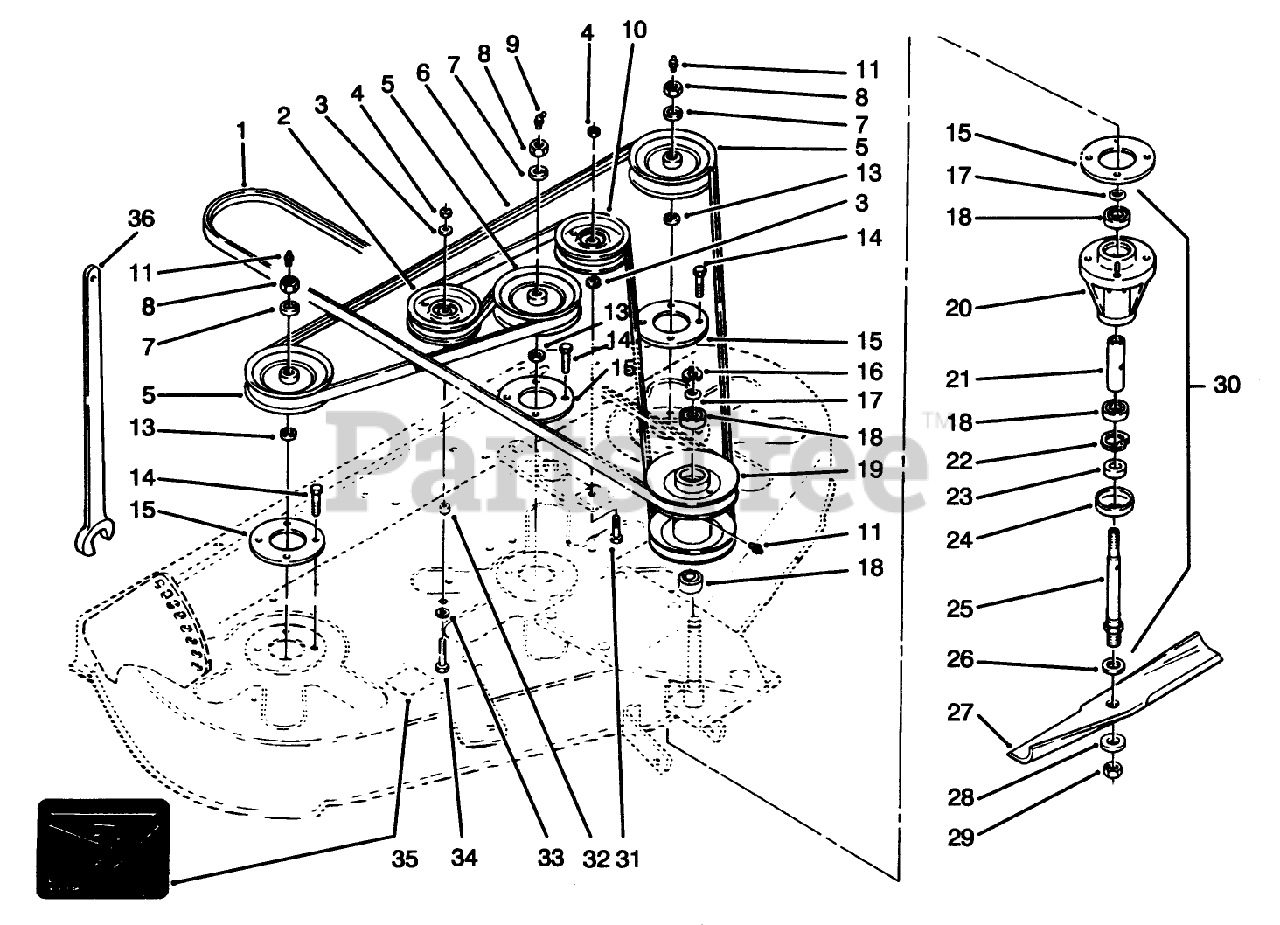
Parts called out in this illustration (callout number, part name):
1	V-BELT
2	Pulley-Idler
3	WASHER-FLAT
4	NUT-LOCK, NI
5	PULLEY-SPINDLE
6	V-BELT
7	WASHER-LOCK
8	NUT-JAM
9	FITTING-GREASE
10	PULLEY-FLAT IDLER
11	FITTING-GREASE
13	Washer
15	SPACER-SPINDLE
16	RETAINING RING
17	O RING
18	BEARING-BALL
19	PULLEY-COUNTER SHAFT
20	HOUSING-SPINDLE
22	RING-RETAINING
23	SPACER-BLADE
24	CUP-SPINDLE
25	SHAFT-SPINDLE
26	Washer
27	BLADE KIT
28	WASHER-FLAT
29	NUT-JAM
30	Spindle Assy. (Incl. Ref. #15, 17, 18 & 20-29)
31	SCREW-HH
32	SPACER
34	SCREW-CARR
35	DECAL-BELT INSTALL
36	Spindle Wrench
